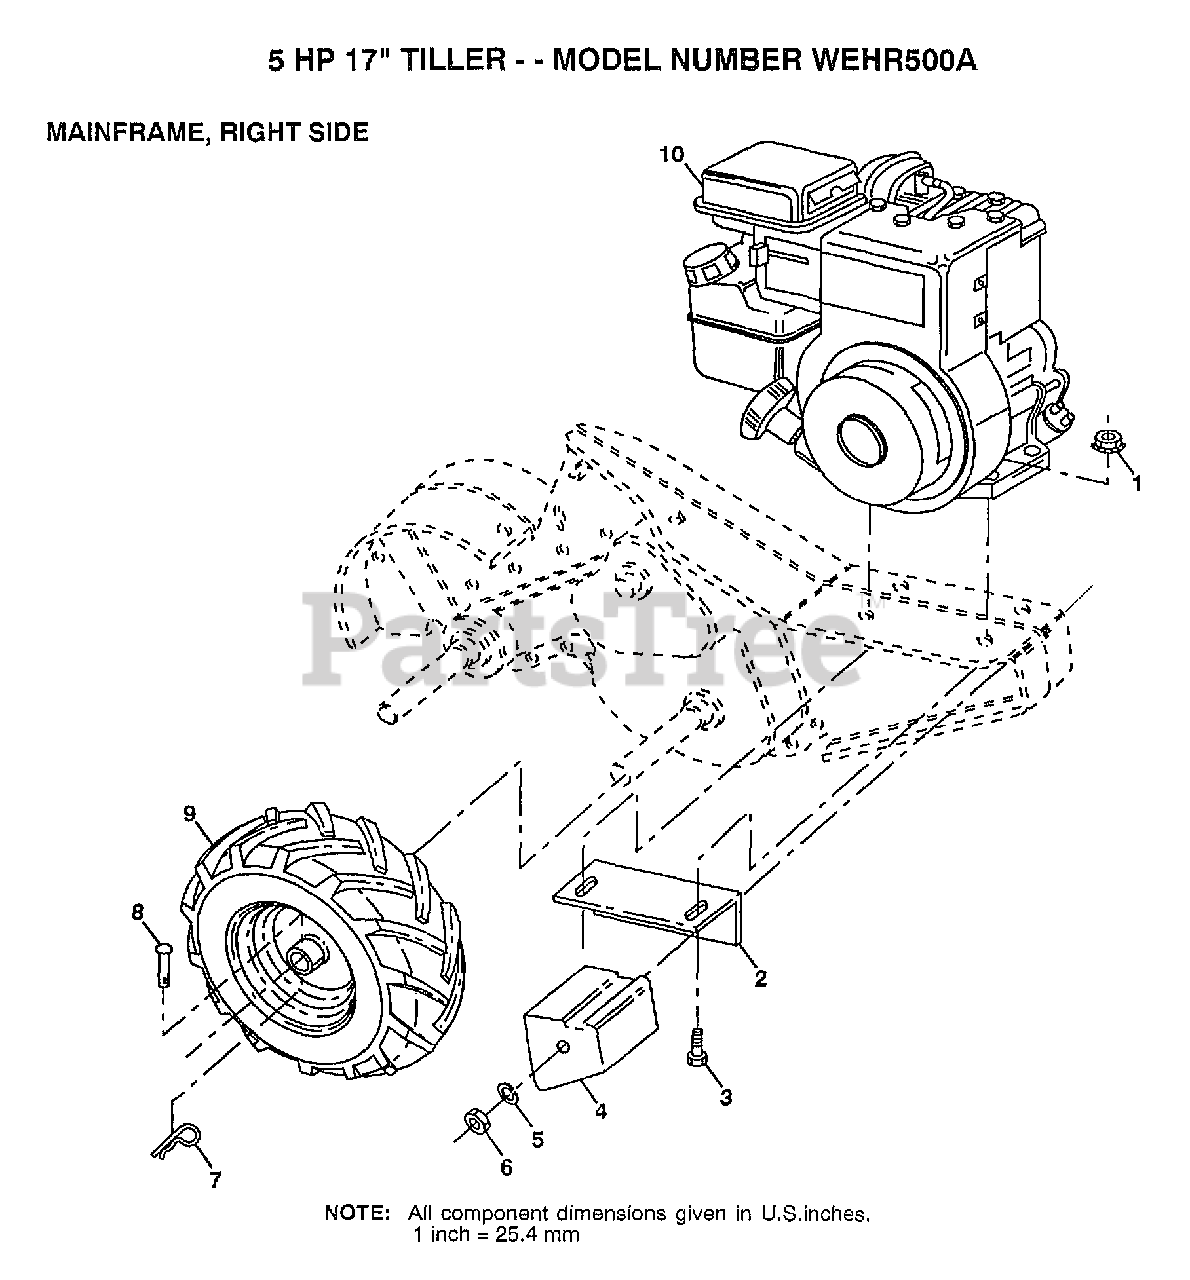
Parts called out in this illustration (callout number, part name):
2	BRACKET RH CRT
3	BOLT.HEX.5/16-1.5
4	COUNTERWEIGHT CRT
5	LOCKWASHER
6	NUT.HEX.3/8-16UNC
7	RETAINER M
8	RIVET.DRILL.1.75
9	TIRE.CHV.13X5.0-6
9	RIM.5X6.YELLOW
